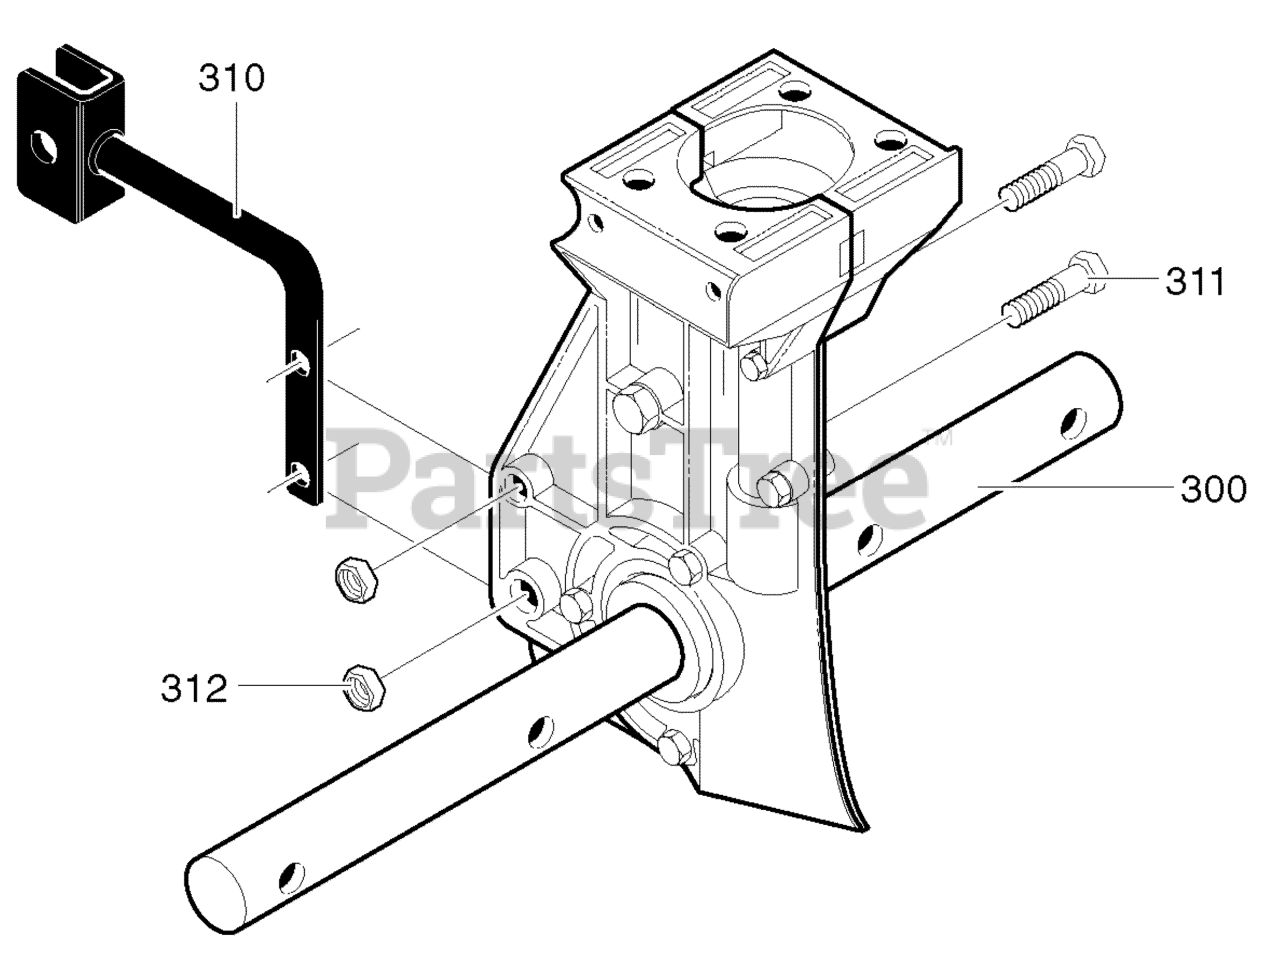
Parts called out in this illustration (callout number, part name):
300	Transmission
310	Bracket, Depth Rod
311	Screw, 1/4-20x1.25
312	Nut, 1/4-20
